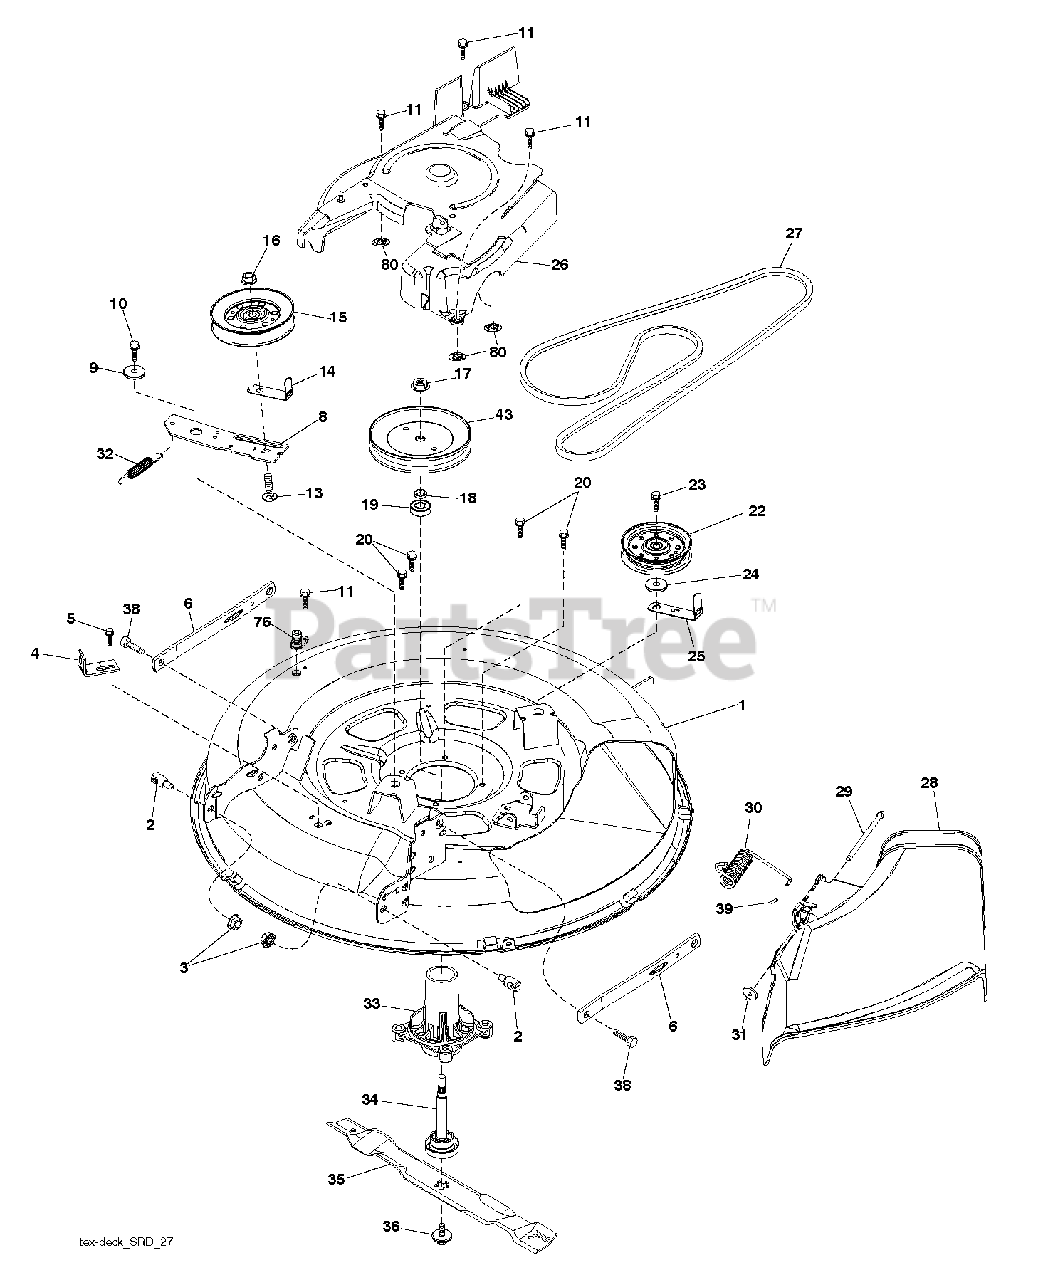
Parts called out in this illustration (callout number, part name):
1	DECK.WELDMENT.PNT.30"SRD
2	STUD.FASTNER.W/ANTI-ROTATE
3	NUT LOCK HEX FLANGE 5/16-18
4	BRACKET.CLUTCH.CABLE
5	BOLT.5/16HEX.WHS.HD
6	ARMS.SUSP.MOWER.REAR.SRD
8	ARM.IDLER.30"SRD
9	SPACER.RETAINER
10	SCREW 3/8-16X1
11	SCREW.1/4-20X5/8
13	BOLT.3/8-16X1.50
14	KEEPER, BELT IDLER
15	PULLEY.IDLER.4.25
16	NUT LOCK FLG 3/8-16 UNC
17	NUT.FLANGE.LOCK.TOP
18	WASHER.SPACER.MANDREL
20	SCREW, WASHER HEAD
22	PULLEY.IDLER.FLAT.46.PR.DR.
23	SCREW LT
24	WASHER
25	KEEPER.BELT.30"SRD
26	COVER.ASM.MANDREL.30"
27	V-BELT.DRIVE.MOWER.30"
28	SHIELD.DEFLECT.MWR.30S.BLACK
29	PIN.HINGE.30".SRD
30	SPRING.TORSION.DEFLECT
31	NUT PUSH M
32	SPRING.MOWER.DRIVE.ELECTRIC
33	HOUSING.MANDREL.4PT.
34	SHAFT.ASM.MDRL.N/GREASE.38
35	BLADE, MULCH.LRV30
36	BOLT.WASHER.ASM.7/16-2
38	BOLT.SHOULDER
39	CAP-SLEEVE LT
43	PULLEY, MANDREL 6.5 PD
76	PORT.WASHOUT
80	PALNUT 1/4
